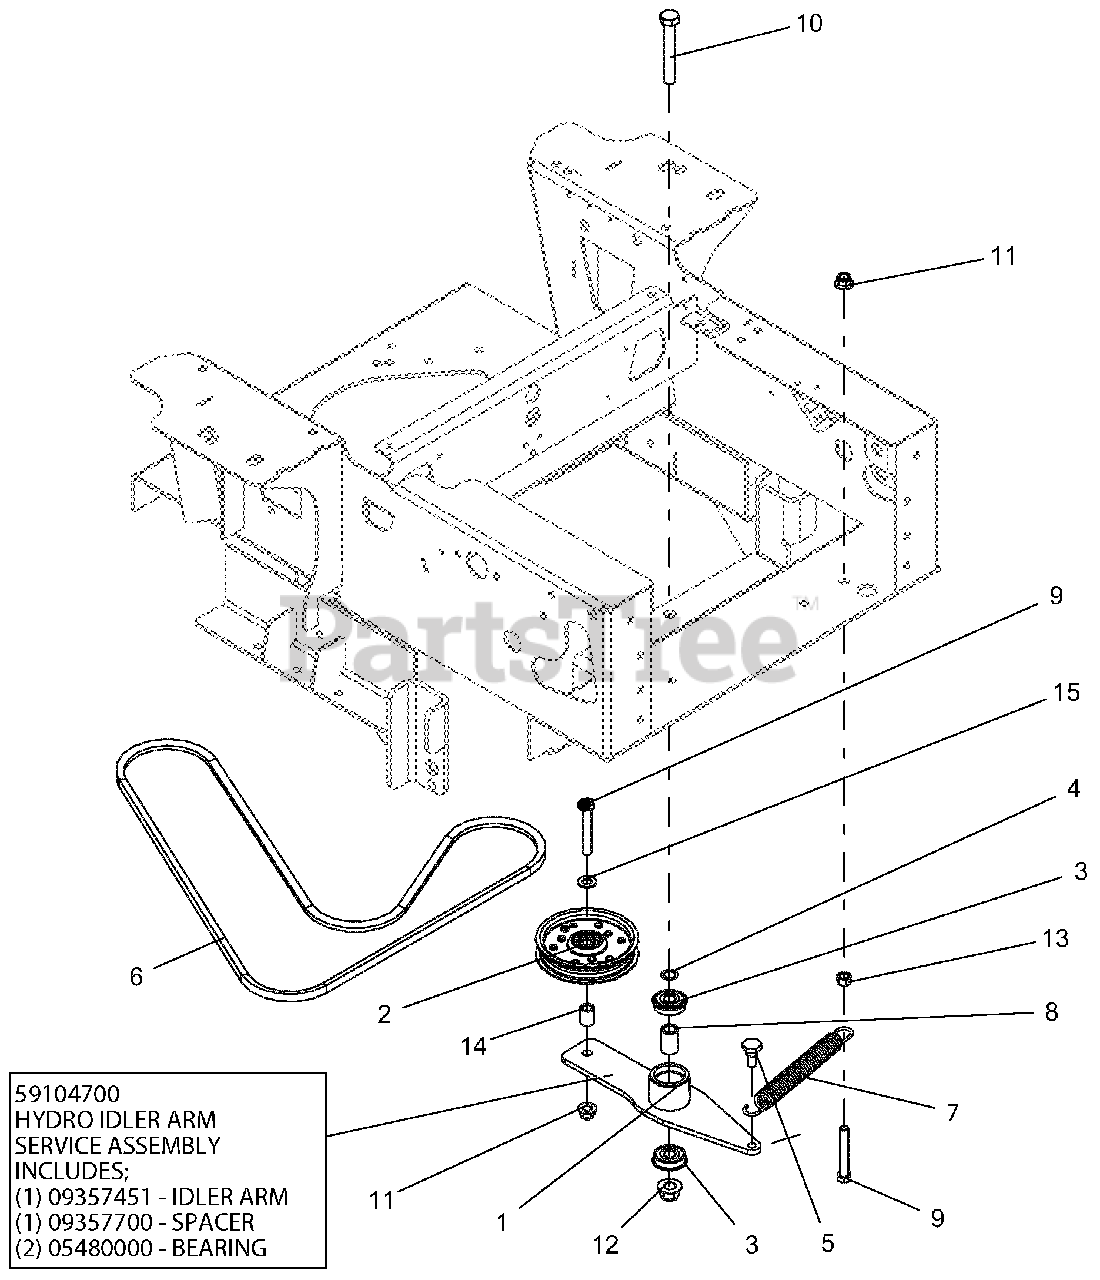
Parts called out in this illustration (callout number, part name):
1	WLDMT, HYDRO DRIVE IDLER ARM-BLACK
1	HYDRO IDLER ARM SERVICE ASSEMBLY
1	IDLER ARM
2	ASM, IDLER 4"
3	BRG, BALL .501 X 1.38 X .438 SEALED
4	WASHER-FLAT-STL, .500 X .750 X .020
5	BLT, SHLDR EP .38-16X.30 HEX YZ
6	BELT, V-A-COGGED
7	SPRG, EXTENSION .120X.845X6.55 WLD
8	SPACER, .510 X .750 X 1.148
9	BLT-HEX .38-16X2.50 GR5 YWZC
10	BLT-HEX .50-13X3.25 GR5 YWZC
11	NUT-LK-NYL-FLG .38-16 YWZC
12	NUT-LK-NYL-FLG .50-13 YWZC
13	NUT-HEX .38-16 YWZC
14	BSHG-SLV .407X.625X.750
15	WSHR-FL-STL.406X.812X.065 YWZ
